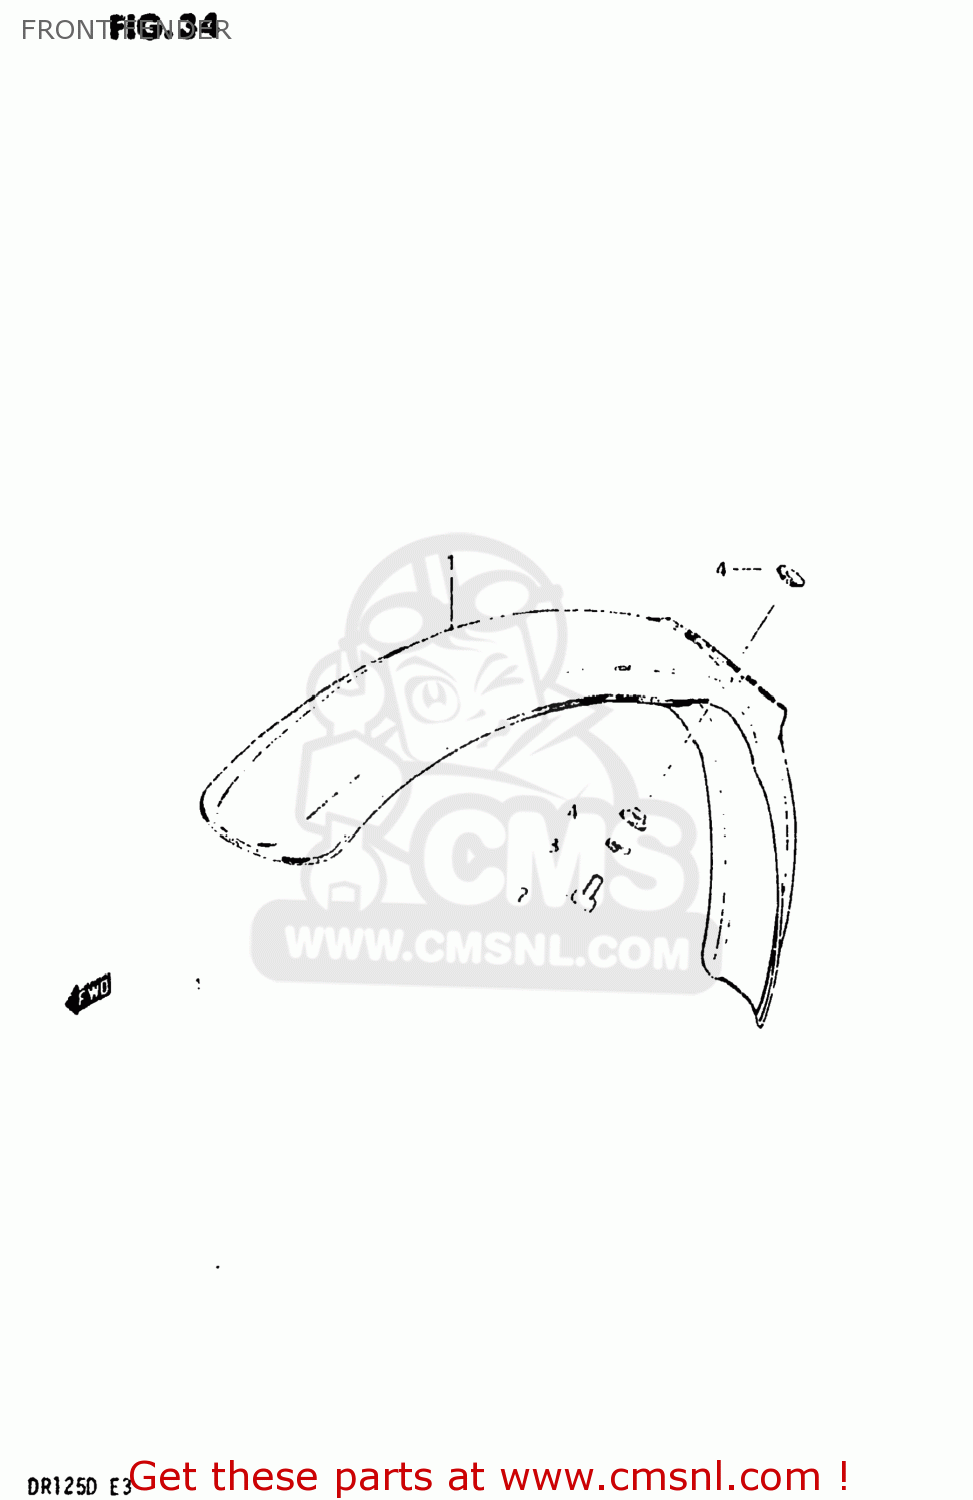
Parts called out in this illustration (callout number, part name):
1	FENDER,FRONT
2	BOLT, UPPER
3	LOCK WASHER
4	SPACER
